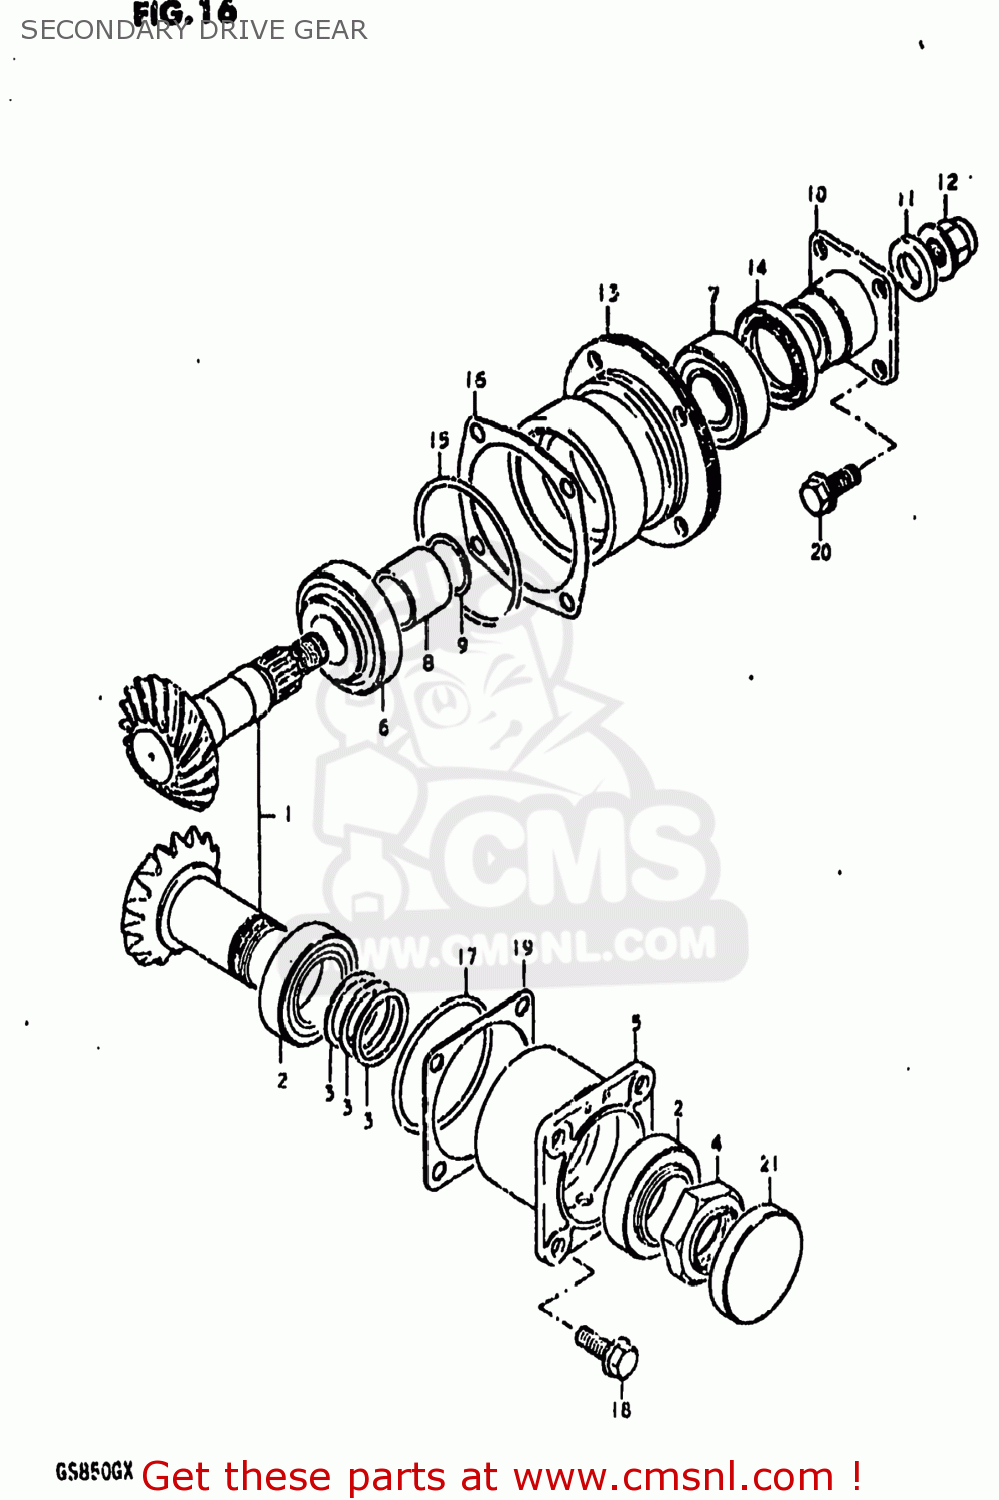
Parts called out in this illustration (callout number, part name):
0	SHIM SET,SECONDARY DRIVE
1	GEAR SET,SECON
2	BEARING(32X58X17)
3	SHIM(32X38X2)
4	NUT
5	HOUSING,SECONDARY DRIVE
6	TAPER,ROLLER BEARING
7	BEARING
8	SPACER (25.2X30X40)
9	SHIM (25X30X2
10	FLANGE,UNIVERSAL JOINT
11	WASHER(14X29X4)
12	NUT
13	HOUSING,SECONDARY DRIVE
14	SEAL,OIL(35X52X9)
15	O RING(D:3.1,ID:69.4)
16	SHIM,DRIVEN GEAR HOUSING
17	O RING(D:2.4,ID:62.6)
18	BOLT
19	SHIM,SECONDARY DRIVE
20	BOLT
21	PLUG
